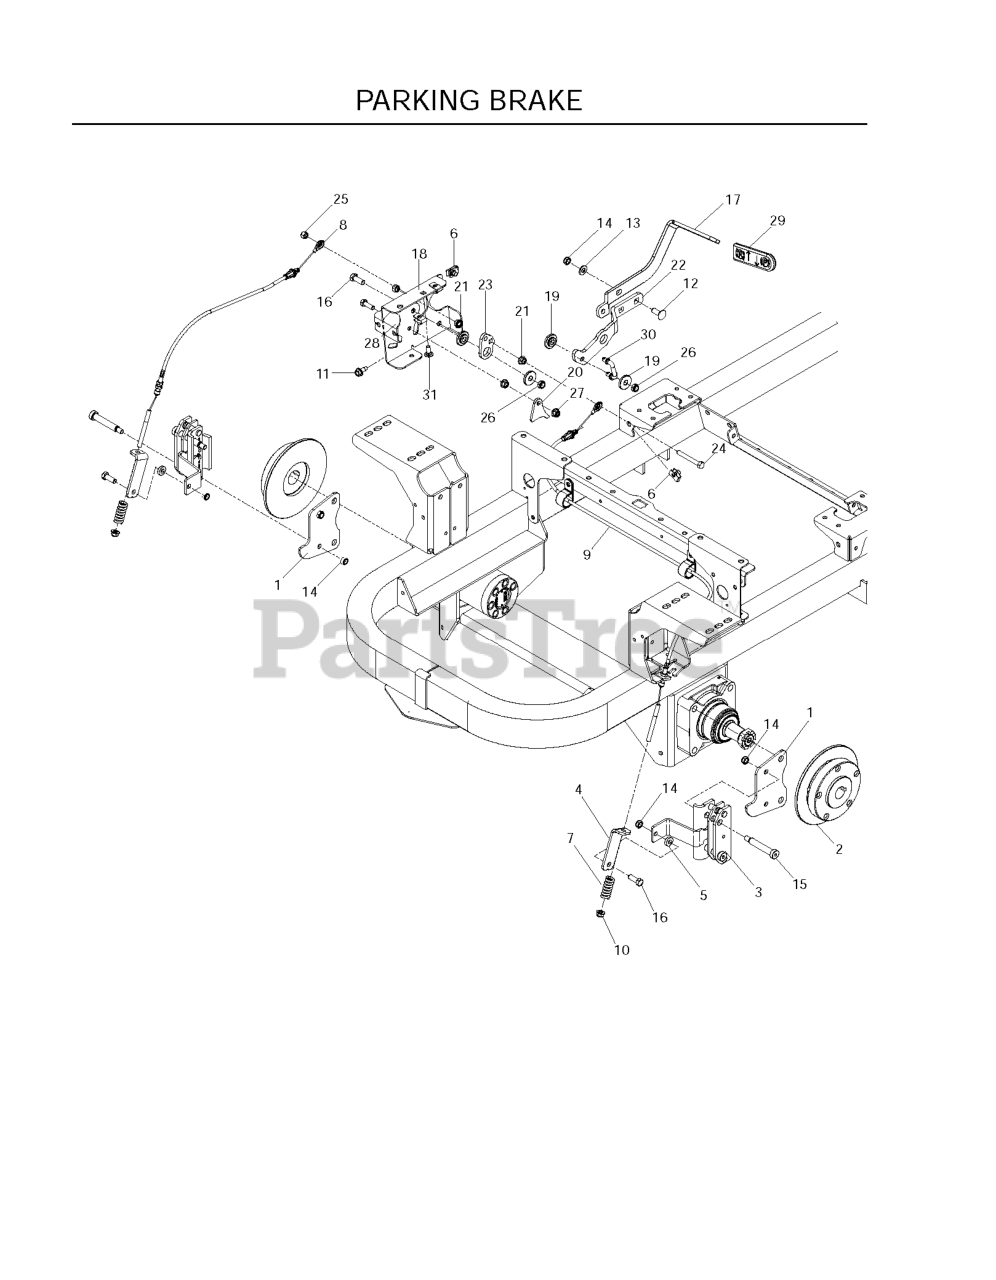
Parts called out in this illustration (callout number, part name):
1	PLATE, BRAKE
2	HUB, 5 BOLT
3	CALIPER PARK BRAKE
4	BRACKET, L
5	WASHER 3/8 X 3/4 X .187 TK
6	U-CLIP 5/16-18 NUT RETAINER
8	CABLE, BRAKE, SHORT
9	RP_CABLE, BRAKE, LONG
10	5/16-18 NYLOC FLANGE NUT
11	BOLT 5/16-18 X 3/4
12	RHSNB 3/8C X 1
13	WASHER 3/8 SAE FLAT
14	NUT HEX 3/8-16 NYLON, THIN
15	SB 3/8-16 X 2-1-1/2 SKT HDD ZD
16	HCS 3/8-16X1.GRD.5.ZD
17	ARM, BRAKE
18	MOUNT, BRAKE WLDMT
19	BUSHING, BRAKE
20	ACTUATOR, SWITCH
21	NUT 5/16C WHIZ
22	LEVER, BRAKE
23	BELLCRANK, BRAKE
24	HCS 5/16-18 X 2 1/2 TPBLT
25	NUT 5/16 NYLOC
26	NUT HEX 3/8-16 NYLON, THIN
27	5/16-18 NYLOC FLANGE NUT
28	HCS 5/16C X 1
29	GRIP, PARK BRAKE
30	LINKAGE, BRAKE
31	BOLT 5/16C X 3/4" CARRIAGE
